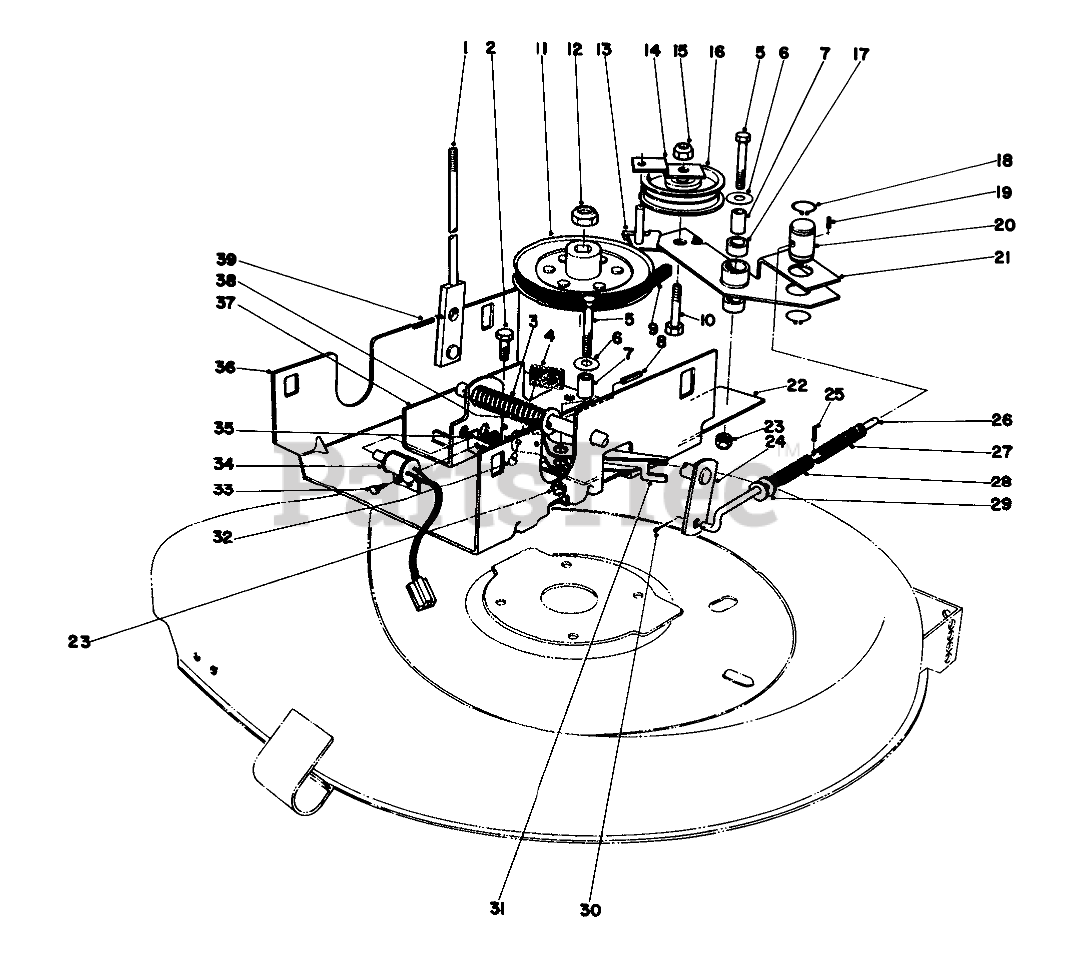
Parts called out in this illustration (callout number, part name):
1	Lever Deck Engagement
2	SCREW-HH
3	COMP SPRING O
4	BLADE BRAKE LINING
5	SCREW-HH
6	WASHER-PLAIN
7	PIVOT SPACER
8	PIN-SPRING
9	V-BELT
10	SCREW-HH
11	DECK PULLEY R
13	Belt Retainer
14	BELT RETAINER UPPER
15	NUT-LOCK, SIDE
16	Flat Idler
17	BUSHING
18	RING-RETAINING
19	PIN-ROLL
20	Pin-Pivot
21	Idler Arm (Incl. Ref. #17)
22	Bracket Idler Mounting
23	NUT-LOCK, NI
24	Linkage
25	PIN-SPRING
26	BLADE ENGAGE ROD
27	Spring Deck Idler
28	Spring Deck Brake
29	WASHER
30	PIN-COTTER
31	Blade Brake (Incl. Ref. #4 & 32)
32	Rivet
34	DECK INTERLOCK SWITCH
35	NUT-KEPS
36	CHANNEL HT ADJ R
37	Mounting Bracket Blade
38	WASHER-FLAT
39	PIN-SPIRAL
